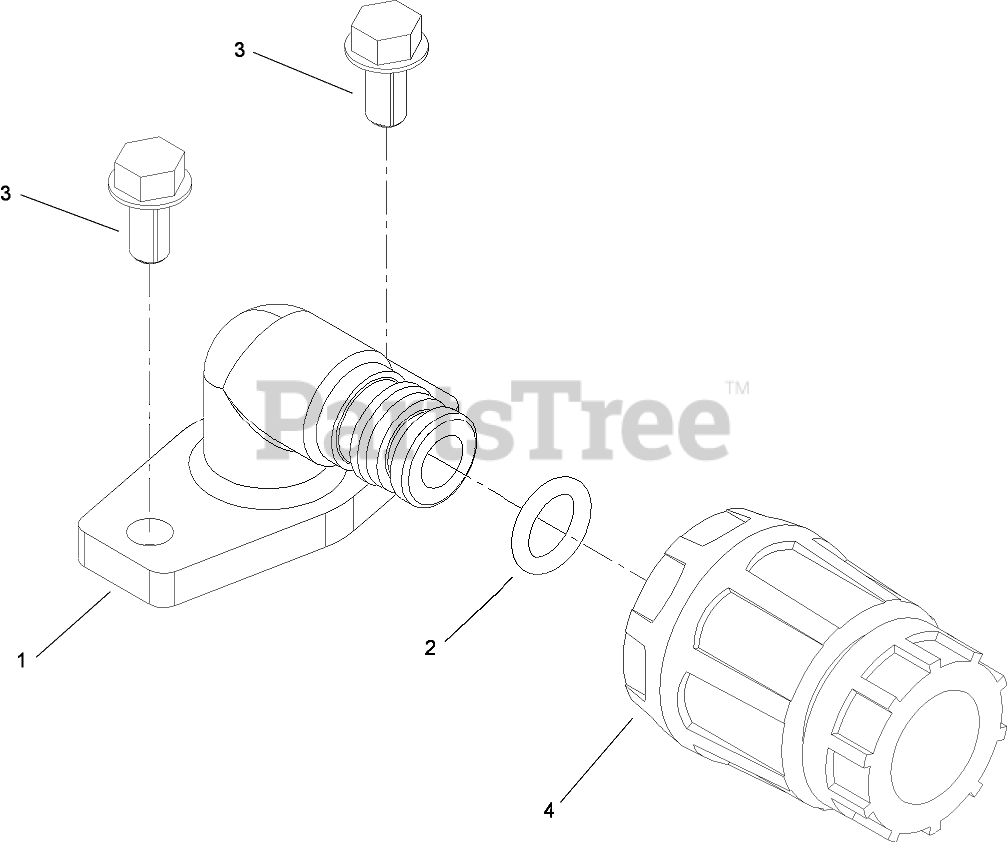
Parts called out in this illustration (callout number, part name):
1	FITTING-WASHOUT
2	O-RING
3	SCREW-HWH
4	CONNECTOR-HOSE
